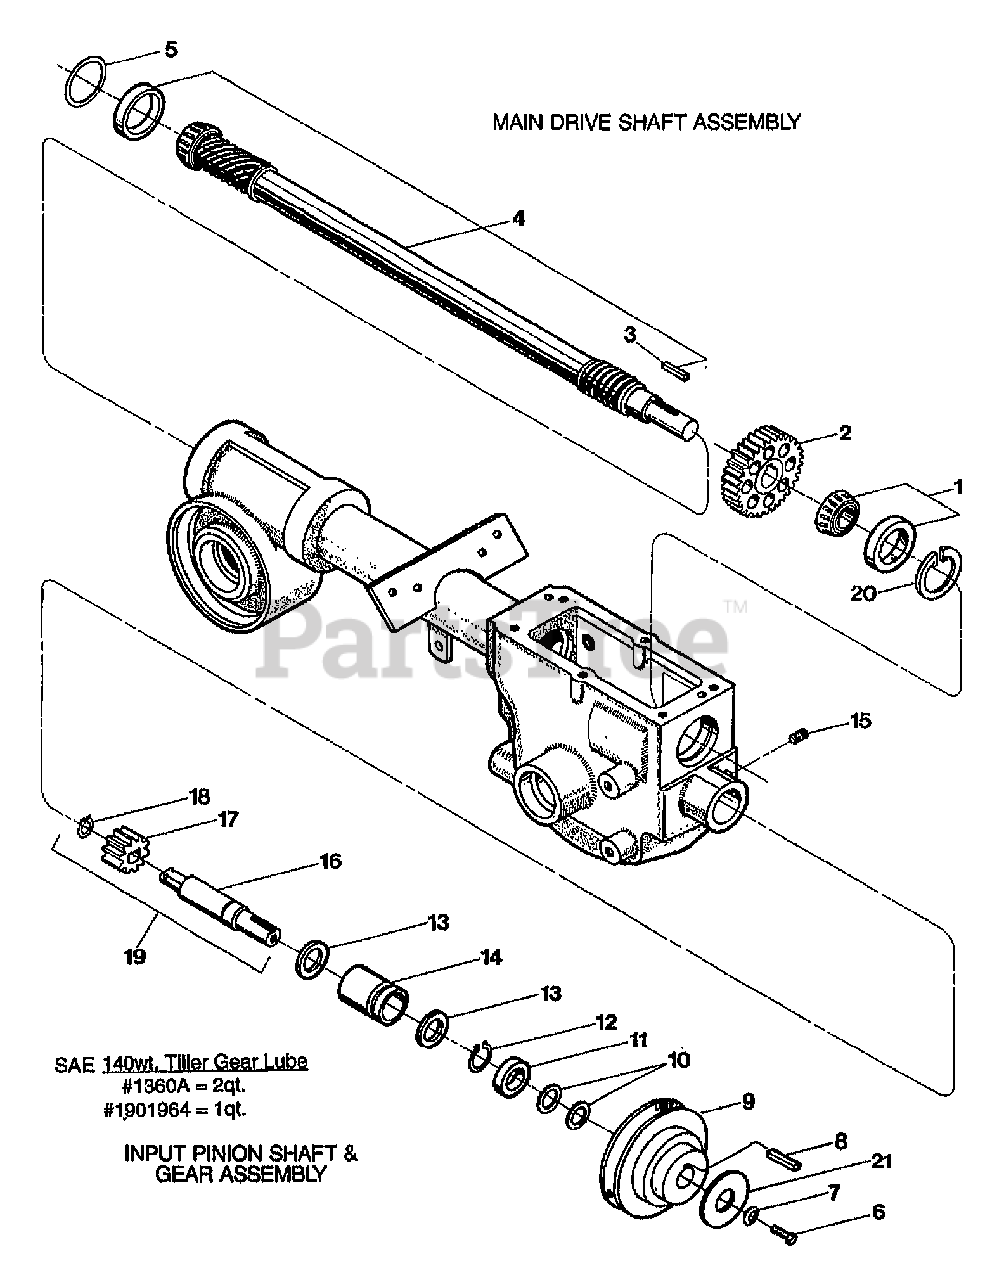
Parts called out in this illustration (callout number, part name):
1	KIT-BRG CONE&RACE-DRIVESHAFT(FRONT OF DRIVE SHAFT)
2	GEAR-SPUR 30 TEETH
3	KEY-.188 SQX1.0
4	KIT-DRIVESHAFT
4	KIT-DRIVESHAFT SMFR
5	SHIM-1.75X1.5X.01 (SEE NOTE 1)
5	SHIM-1.75X1.5X.03 (SEE NOTE 1)
5	SHIM-1.75X1.5X.005 (SEE NOTE 1)
5	SHIM SET-DRIVESHAFT-HORSE
6	SCR-HH 5/16-24X.75 G5 ZP
7	WASHER-.827X.331X.098 (CONCAVE SURFACE ( FACES PULLEY)
8	KEY-.188 SQX1.0
9	PULLEY-TRANS MACH
10	WASHER # .875 X .65 X .06
11	SEAL-PINION SHAFT PT/85030/00
12	RING-RETAIN EXT .707 ID
13	WASHER-1.022X.752X .059
14	BUSHING-1.24X.75X1.8 GRVD
15	SCR-SS 5/16-18X.375
16	SHAFT-PINION(P-V)
17	GEAR-PINION P/M
18	RING-BOWED EXT .461 ID
19	PINION W/GEAR&SNAP RING
20	RING-RETAINING 5000-181
21	WASHER-2.5X.316X.06
